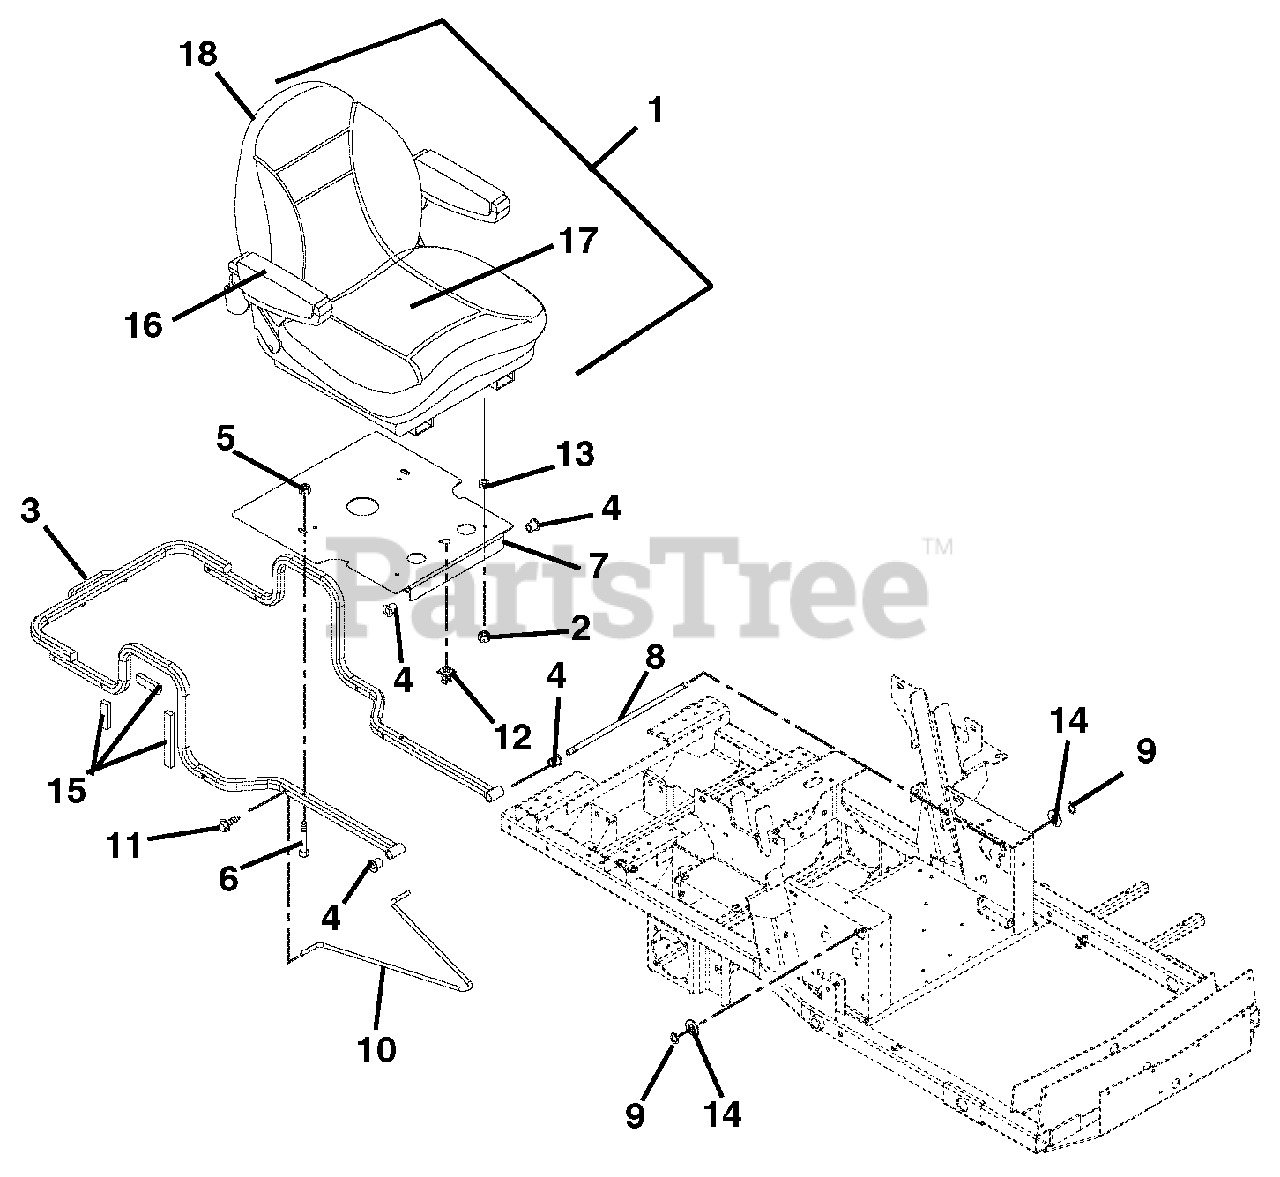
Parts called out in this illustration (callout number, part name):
1	Seat, Suspension
2	Nut, Locking Top Flange .31-18
3	Weldment, Hood Frame
4	Bushing, Flange .515 x .750 x .745 x 1.00
5	Nut, Locking Top Flange .38-16
6	Bolt, Rib Neck .38-16 x 1.50
7	Weldment, Seat Pivot Mount
8	Rod, Seat Frame Pivot
9	Ring, Retaining External .500 x .050
10	Rod, Prop
11	Screw, Tapping .25-20 x .50 Hex Washer Head
13	Bushing, Sleeve .377 x .624 x .235
14	Washer, Flat Steel .531 x 1.06 x .095
15	Tape, VHB
16	Kit, Arm Pad (1 per bag)
17	Kit, Seat Cushion
18	Kit, Back Cushion
